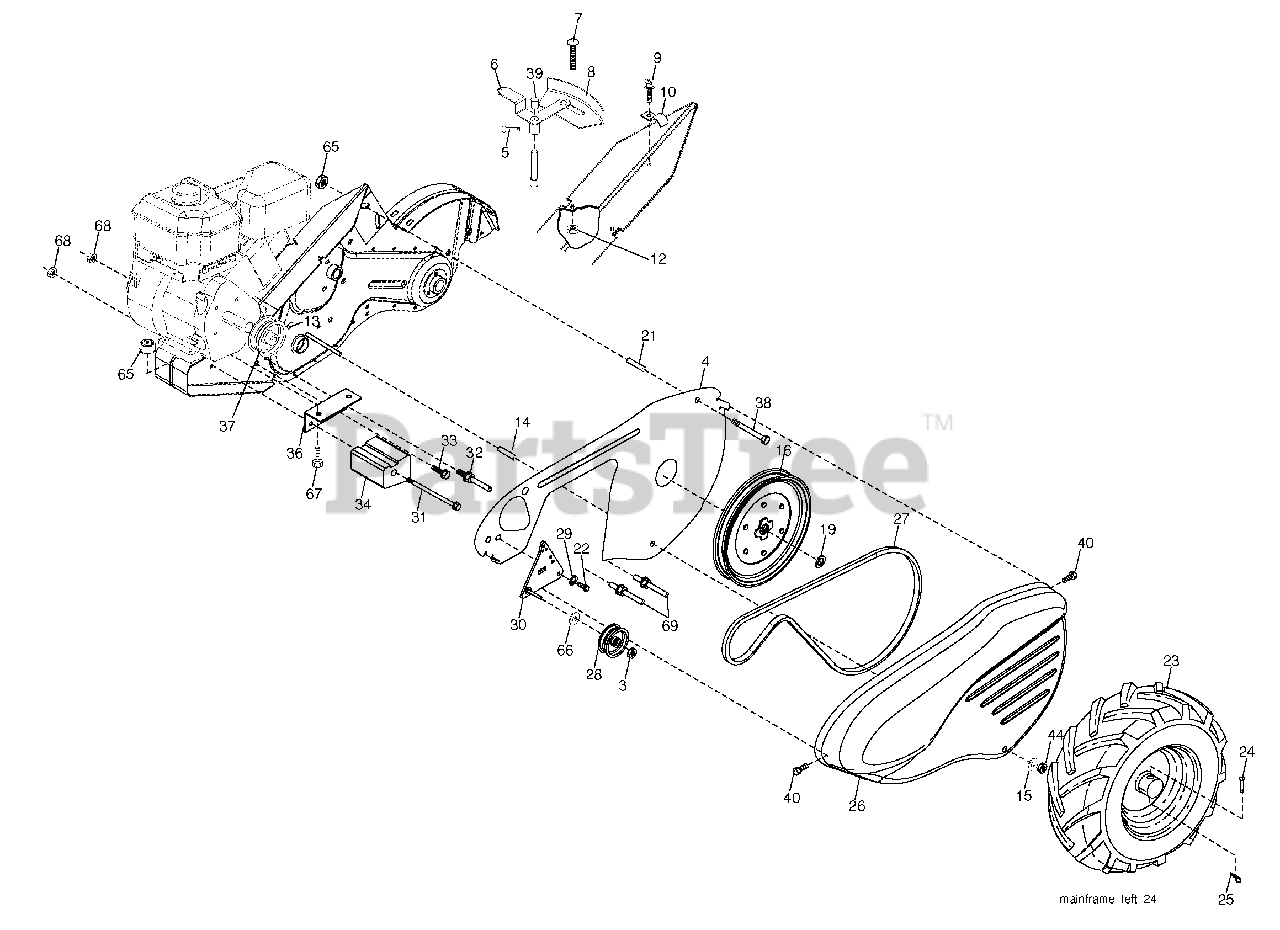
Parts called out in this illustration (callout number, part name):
3	Nut, Hex 3/8-16
4	Shield, Inner Belt Guard RT
5	Screw, Shift Lever
6	Lever, Shift
7	Bolt, Carriage 1/4-20 x 1/2 Gr. 5
8	Plate, Shift Indicator
9	Screw, Hex, Washer Head, Slotted #10-24 x 1/2
10	Clip
12	Nut, Keps Hex 1/4-20 unc
13	Screw, Set, Hex 5/16-18 x 3/8
14	Spacer, Split 0.327 x 0.42 x 1.220
15	Washer 11/32 x 11/16 x 16 Ga.
16	Sheave, Transmission
19	Retainer, Ring
21	Spacer, Split 0.327 x 0.42 x 2.09
22	Bolt, Fin Hex 5/16-24 unf x 1/2
23	Tire
23	Rim
23	Tire Valve
24	Rivet, Drilled
25	Clip, Hairpin
26	Guard, Belt
27	Belt, V
28	Pulley, Idler
29	Ring, Klip
30	Bracket, Idler
31	Bolt, Hex 5/16-16 x 12
32	Shaft, Idler Arm
33	Bolt, Hex 3/8-16 x 1
34	Counterweight, L. H.
35	Bolt, Hex 5/16-18 x 1-3/4
36	Bracket, Reinforcement, L. H.
37	Sheave, Engine
38	Bolt, Fin Hex 5/16-18 unc x 2-3/4
39	Cap, Plunger Blk
40	Screw Hex Wsh Slt #10-24 x 1/2
44	Nut Lock Hex w/Ins 5/16-18 unc PL
65	Nut Lock Hex Flange
66	Washer 13/32 x 13/16 x 12 Ga.
68	Nut Keps Hex 3/8-16 unc
69	Keeper Belt Engine
